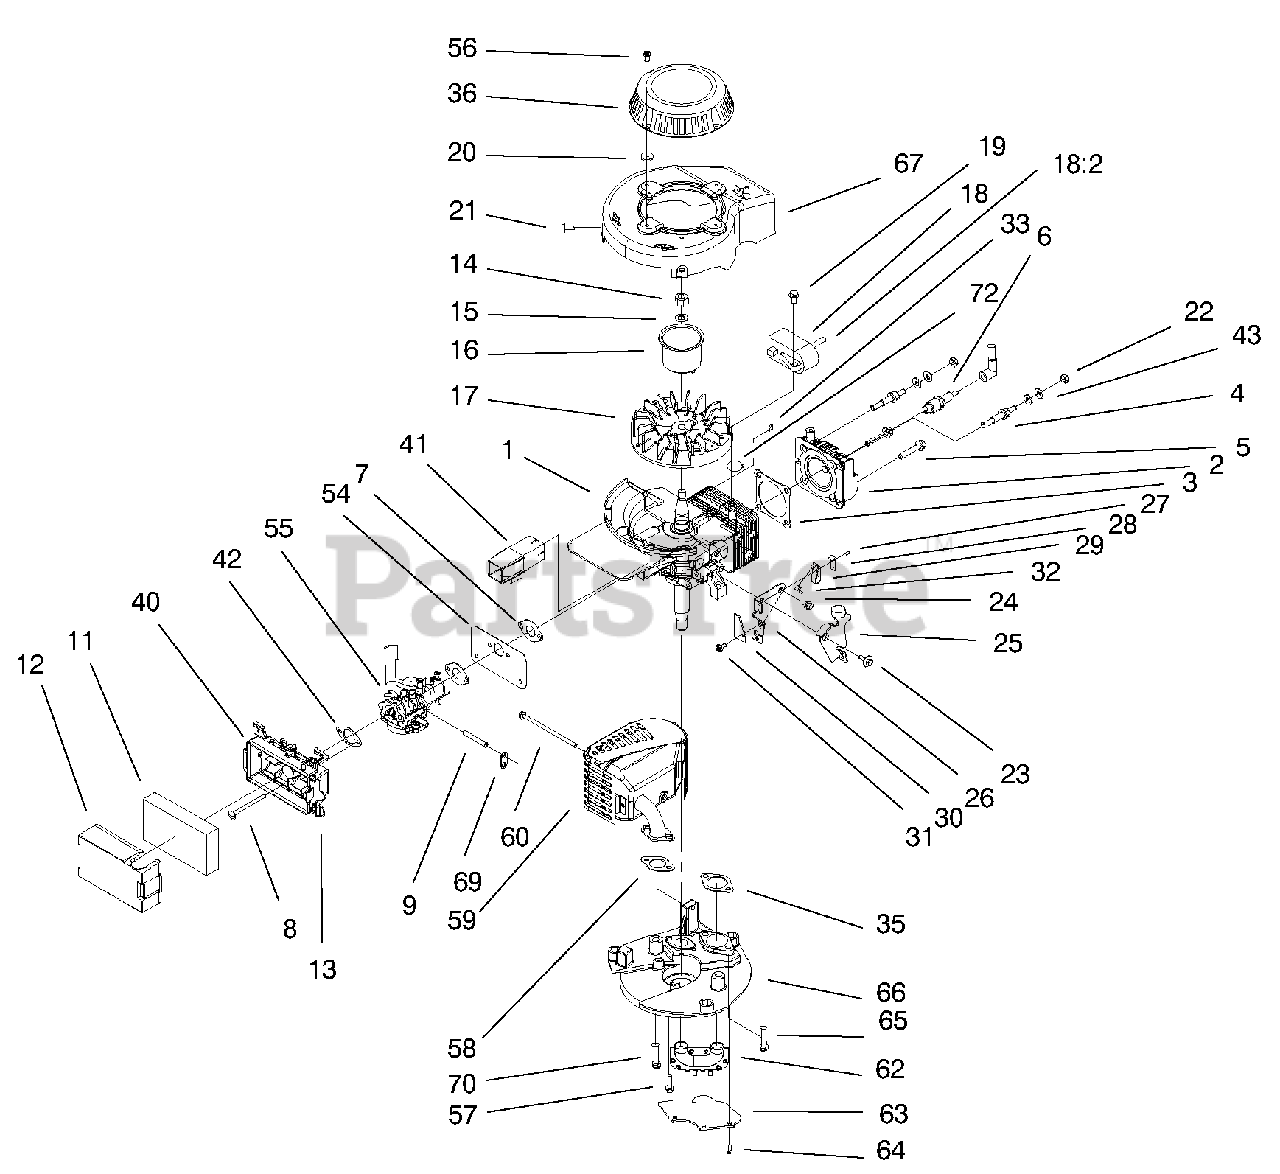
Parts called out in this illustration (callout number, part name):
3	Gasket-Head
5	Bolt-Head
6	Plug-Spark
7	Gasket-Intake
9	Primer Hose
11	Filter-Air
12	Cover-Air Filter
13	Retainer
15	Washer-Lock
16	Hub Starter
17	Flywheel
18	Ignition
18:2	Lead&cover
18:2	Cover & Term. ASM
21	Screw-HH
23	Screw-Shoulder
24	Screw-HWH
25	Brake Plate ASM
26	Plate-Brake
27	Rivet-Plastic
28	Strap-Insulation
29	Strap-Ground
30	Stop-Strap
31	Screw-Special
32	Wire-Lead
35	Gasket-Exhaust
36	Starter ASM
40	Base ASM
42	Gasket-Filter
43	Washer-Belleville
54	Shield-Carb.
55	Carburetor ASM With Gaskets
56	Screw Sems
59	Muffler And Guard ASM
59:4	Screw-HWH
59:5	Washer-Lock/Int
60	Bolt-Console
62	Pipe-Transfer
63	Cover-Muffler
64	Screw-HH
65	Screw-HH
66	Mounting Plate
67	Shroud ASM
69	Hose-Retainer
70	Screw HWH
72	Strap-Tie
